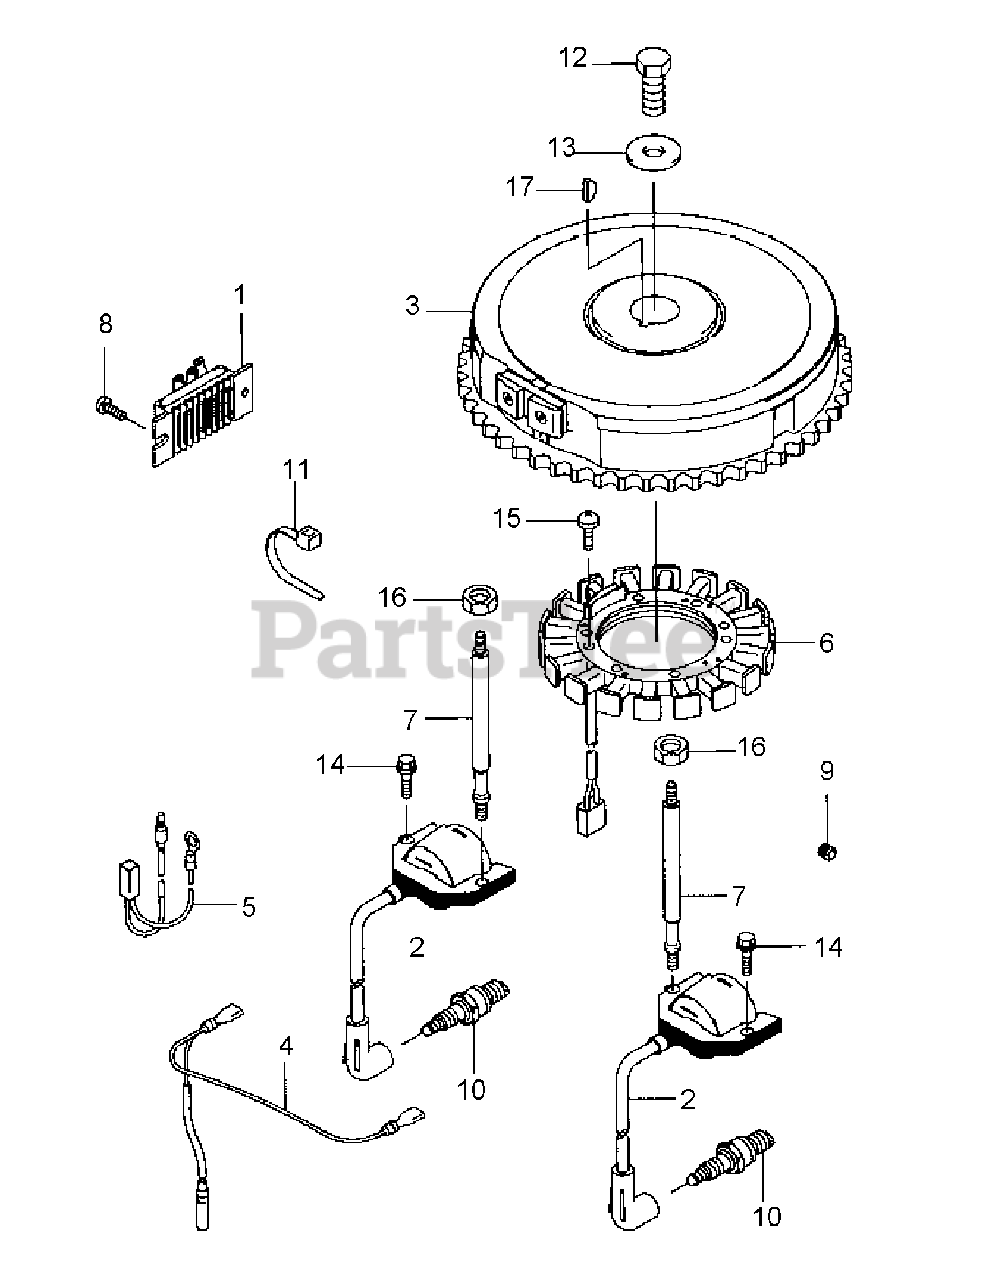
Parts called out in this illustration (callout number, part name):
1	VOLTAGE REGULATOR
2	IGNITION COIL ASSY.
6	CHARGING COIL
7	STUD
10	SPARK PLUG
14	FLANGED BOLT
15	PAN SCREW
17	WOODRUFF KEY
